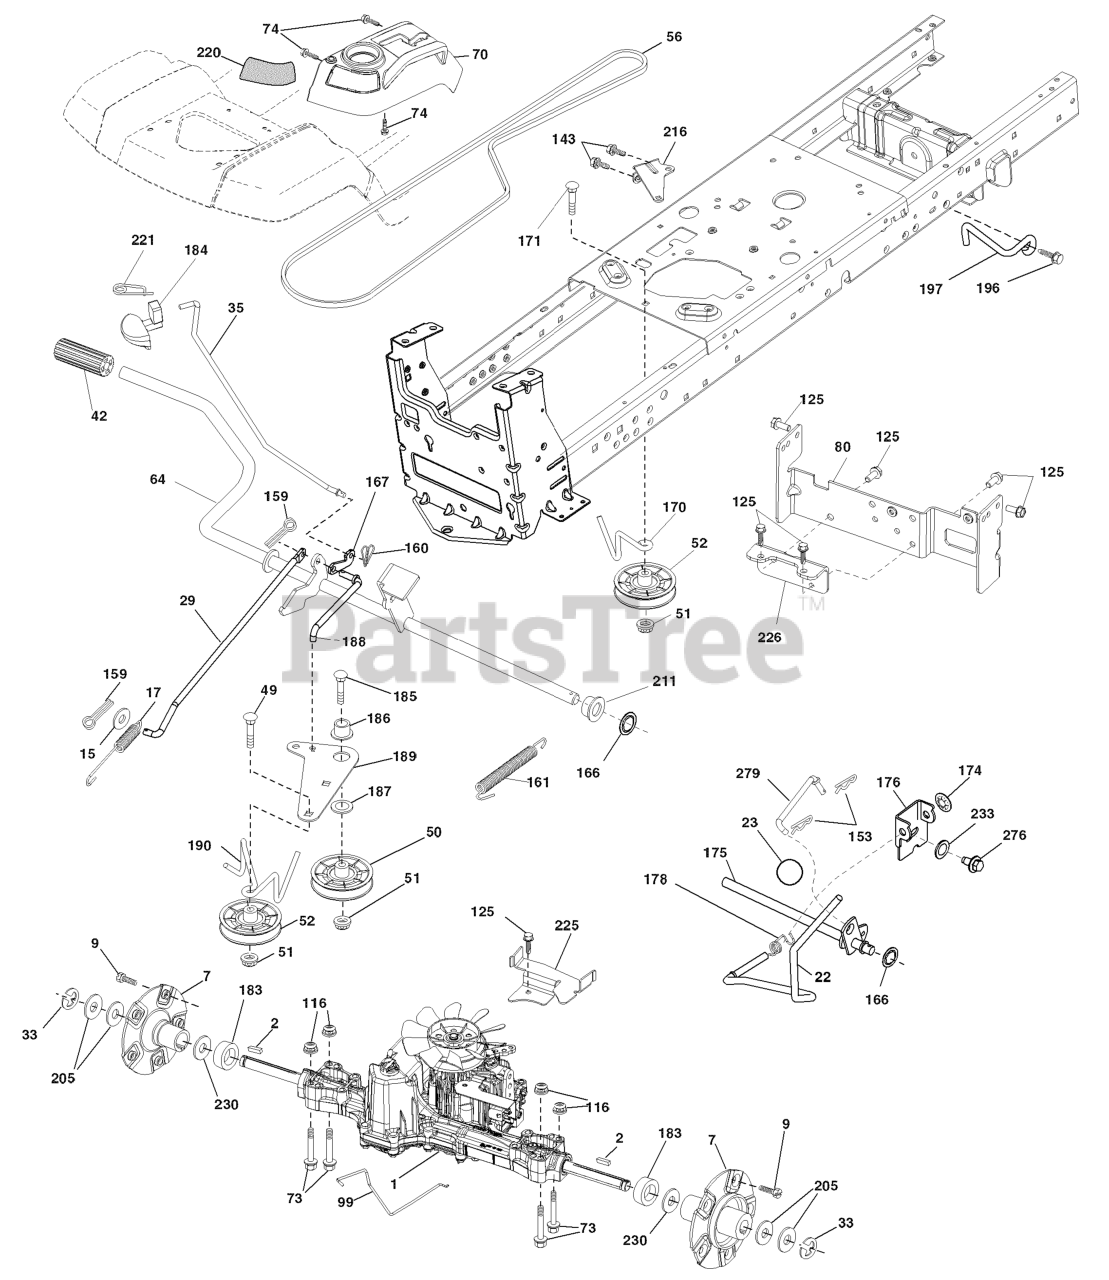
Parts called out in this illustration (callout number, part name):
1	TRANSAXLE.K66.AD.FCH.TG
2	KEY 1/4 X 2.5
7	HUB.ASM.WHEEL.REAR.23"TEX
9	HUB BOLT
15	WASHER
17	SPRING.BRAKE.K46
22	ROD.SHIFT.FENDER.STGT.
23	KNOB.DELUXE.(PISTOL.GRIP).BLAC
29	ROD.BRAKE.K66
33	E RING HYT
35	ROD.BRAKE.PARKING.GT.H
42	PEDAL COVER T
50	IDLER.FLAT.910.OFFSET
51	NUT LOCK FLG 3/8-16 UNC
52	IDLER.V-GROOVE.910.OFFSET
64	SHAFT.ASM.PEDAL.BRAKE.
70	RP CONSOLE.ASM.HYDO.HUSQ.
73	BOLT HEX 5/16-18 GR 5
74	SCREW.HI-LO.CONSOLE
80	STRAP.TORQUE.K66
99	ROD.SPRING.BYPASS.K66.GT.Z
116	NUT LOCK HEX FLANGE 5/16-18
125	SCREW
143	Screw 5/16-18 x 1/2
153	RETAINER M
159	COTTER PIN
160	RETAINER CLIP
161	SPRING, RETURN LT
166	NUT.PUSH.625.2006
167	LATCH.BRAKE.SPRING
170	KEEPER.V-IDLER.CENTER.
171	BOLT
174	NUT.PUSH.500.2006
175	SHAFT.ASM.SHFT.T2.TLT
176	ARM.CLEVIS.ROD.SHIFT
178	SPRING.SHIFT.GT2006
183	SPACER.AXLE.HG.TEX
184	HANDLE.PARKG.BRK.HUSQ X667
185	BOLT
186	SPACER.RETAINER
187	WASHER 12/32X2X10GA
188	RP.LINK.CLUTCH.GROUND.DRIVE
189	BELLCRANK.GROUND.DRIVE.TEX.
190	KEEPER.BELLCRANK.DRIVE
196	SCREW 3/8-16X1
197	BRKT.ANIT-ROTATION.CLUTCH
211	BUSHING.SHAFT.BRAKE.HAND
216	BRACKET.PULLEY.IDLER.W/TEX
220	REFLECTOR.RH.TEX GT
221	RETAINER.SPRING.CLIP.H
225	KEEPER.BELT.TRANSAXLE.K66
226	BRACKET.MOUNT.TORQUE.K66.TG
233	WASHER SERRATED
276	BOLT FIN HEX 7/16-14 X 1
279	LINK.ASM.SHIFT.FENDER.K66
